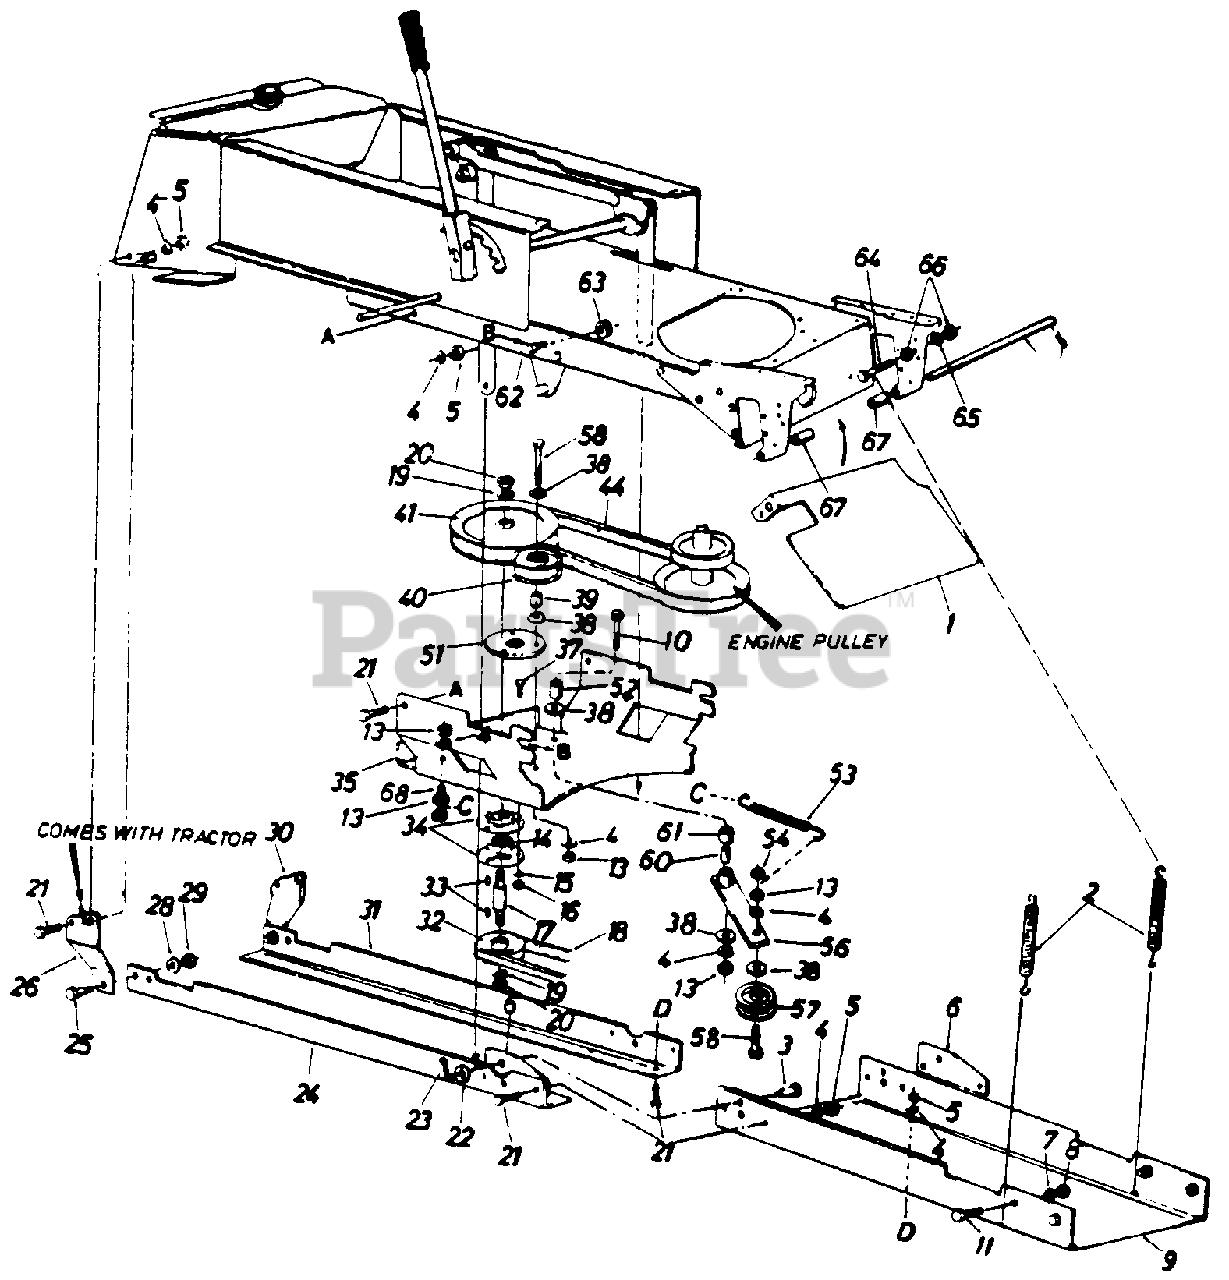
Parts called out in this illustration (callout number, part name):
3	Clevis Pin
4	L.-Wash. 318" I.D.*
5	Hex L.-Nut 3/8-24 Thd.
6	Attaching Plata
7	L.-Wash. 112" I.D.*
8	Hex L-Nut 1/2-20 Thd.
11	Hex Eblt 112-20 x 1.25" Lg.*
13	Hex Jam Nut 3/8-18 Thd.
14	Ball Bearing
15	L.-Wash. 5/16" I.D*
16	Hex Nut 5/16-18 Thd.*
17	Spindle
18	"V"-Bdt
19	L-Wash. 5/8"I.D.*
20	Hex Jam Nut 518-11 Thd.
21	Hex Bolt 318-24 x 1.00" Lg.*
23	Intemal Cottar Pin
29	Hex Nut 7/16"-14 Thd.
33	#6 Hi-Pro Key 3/16 x 5/8" Dia.
34	Bearing Housing
35	Supporting Bracket
37	Hex Sems Bolt 5/16-18 x 1"*
38	Fl.-Waah. .38" I.D. x l" O.D.
39	Spacer .38" I.D. x .62' O.D.
40	Fl.-idler Pulley
41	Upper Drive Pulley
44	"V"-Belt
53	Extension Spring 4.75" Lg.
54	Hex Cent. L.-Nut 3/8-16 Thd.
56	Idler Arm Ass'y.
57	Idler Pulley
58	Hex Bolt 3/8-16 x 2.25" Lg.
60	Spacer.377" I.D. x .83" Lg.
61	Spacer.38" I.Q x .565" Lg.
62	Shoulder Bolt .498 Dia.
63	Hex Cent. L-Nut 3/8-16 Thd.
64	Hex Bolt 11428 x 1.50" Lg.
65	L-Wash. 1/4" I.D.
66	Hex Nut 1/4-28 Thd.
67	Spacer .63" I.D. x 1.75" Lg.
68	Hex Bolt 3/8-16 x 2" Lg.
